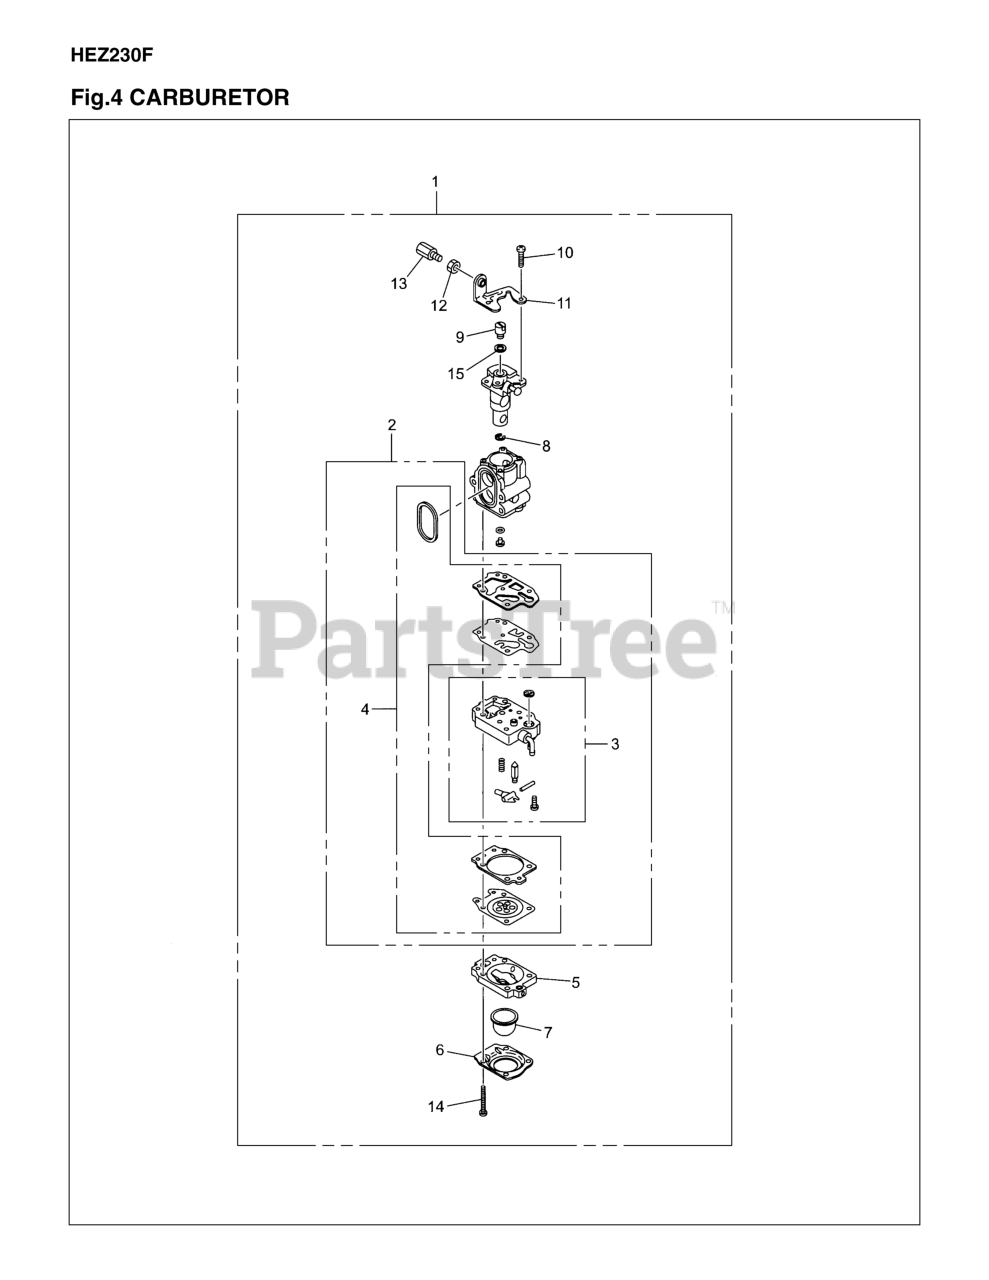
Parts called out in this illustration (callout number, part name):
1	CARBURETOR ASSY
2	REBUILD KIT
3	CARBURETOR BODY
4	GASKET KIT
6	1OVER
8	RING
9	SWIVEL
10	SCREW
11	BRACKET
12	NUT
13	ADJUSTER
15	WASHER
